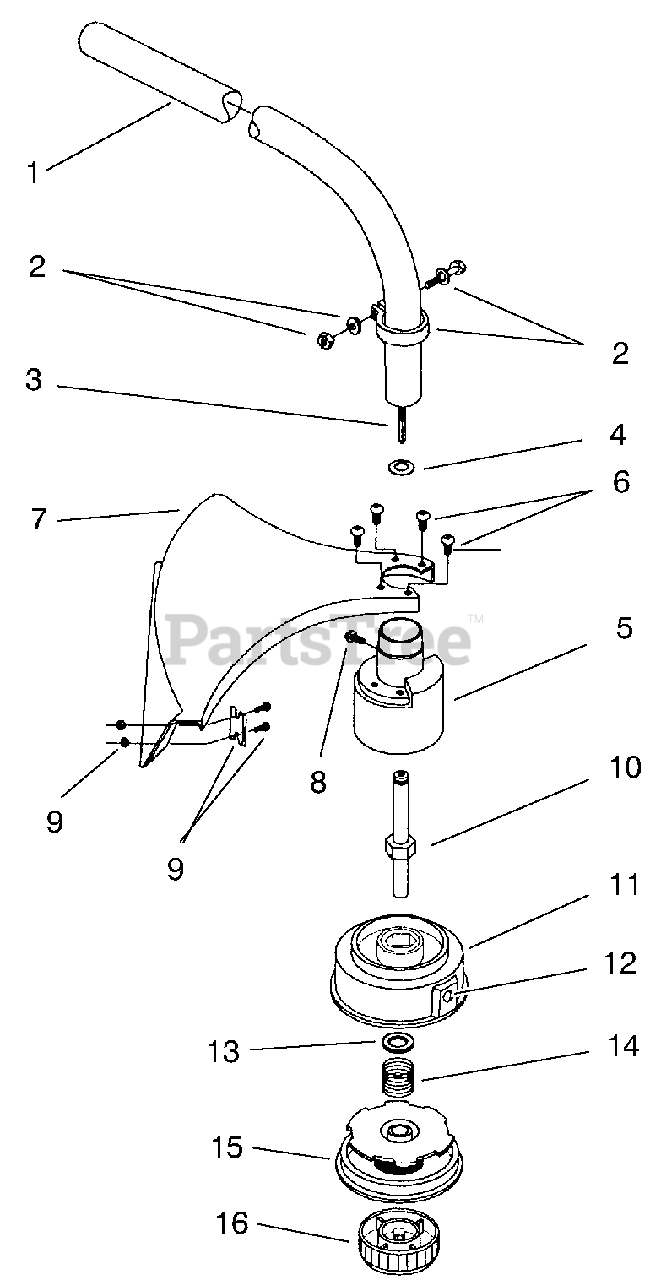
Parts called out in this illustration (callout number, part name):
1	Drive Shaft Housing Asm.
2	Lower Clamp Assembly
3	Lower Flexible Drive Shaft
5	Bushing Housing Assembly
6	Guard Mounting Screw Asm.
7	Guard and Blade Assembly (Incl. Ref. # 9)
8	Anti-Rotation Screw
9	Blade Assembly
10	Spool Shaft
11	Outer Spool and Eyelet Asm. (Incl. Ref. #12)
13	Retainer
15	Inner Reel
16	Bump Head Knob Assembly
